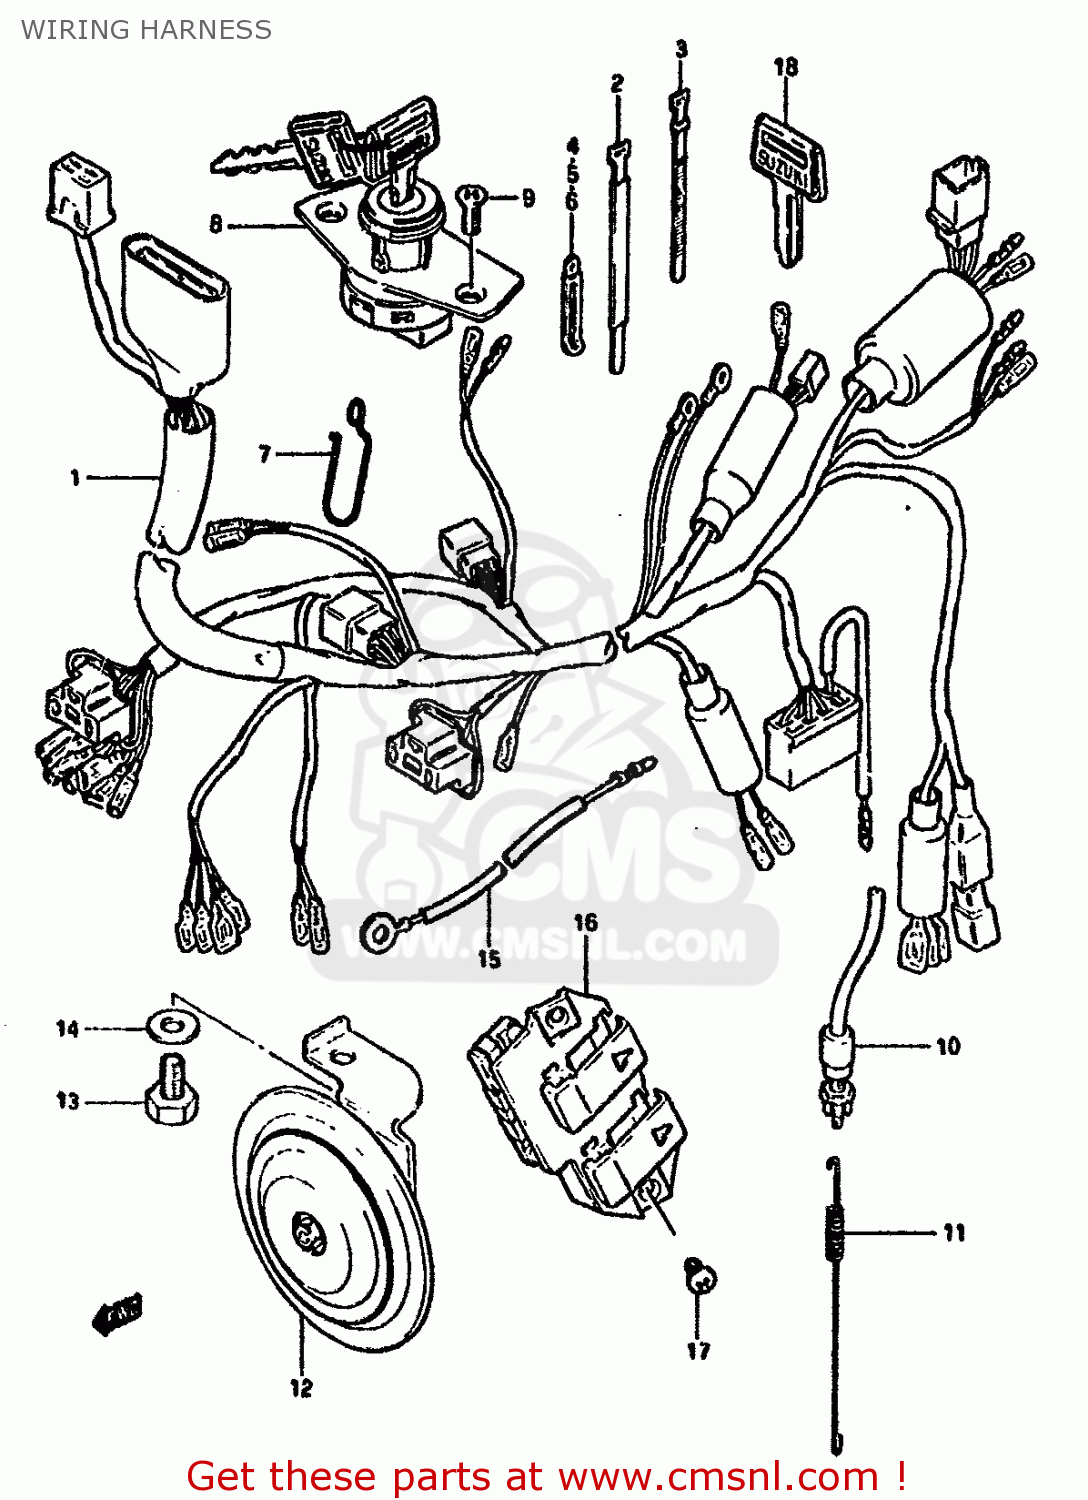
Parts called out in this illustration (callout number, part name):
1	WIRING HARNESS
2	CLAMP
3	CLAMP(L:80)
4	CLAMP
5	CLAMP
6	CLAMP
7	BOOT,WIRING HARNESS
8	SWITCH ASSY,IGNITION
9	SCREW
10	SWITCH ASSEMBLY,STOP LAMP
11	SPRING
12	HORN
13	BOLT 8X12
14	WASHER
15	WIRE
16	SWITCH ASSY,SIDE COVER,L
17	SCREW
18	KEY,BLANK
